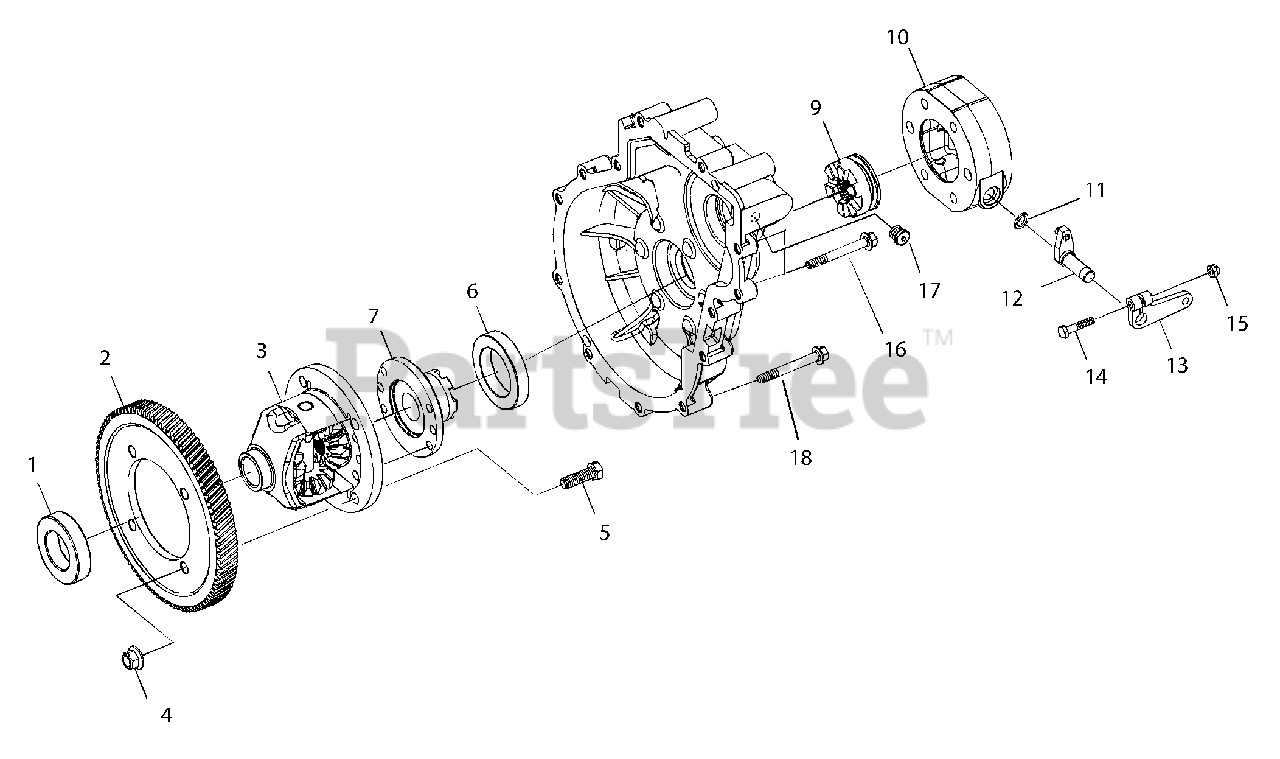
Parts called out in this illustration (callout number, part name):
1	Bearing, Bal
2	Gear, Helical (Ring)
3	Assembly,Differential
6	Bearing, Bal
7	Flange, Half, Differential
8	Screw,Socket Head
9	Gear, Clutch Differential Lock
10	Housing, Differential Lock
12	Assembly, Shift Shaft
13	Lever, Actuating
14	Screw, Hex Head
16	Screw, Flange Head
18	Screw, Flange Head
